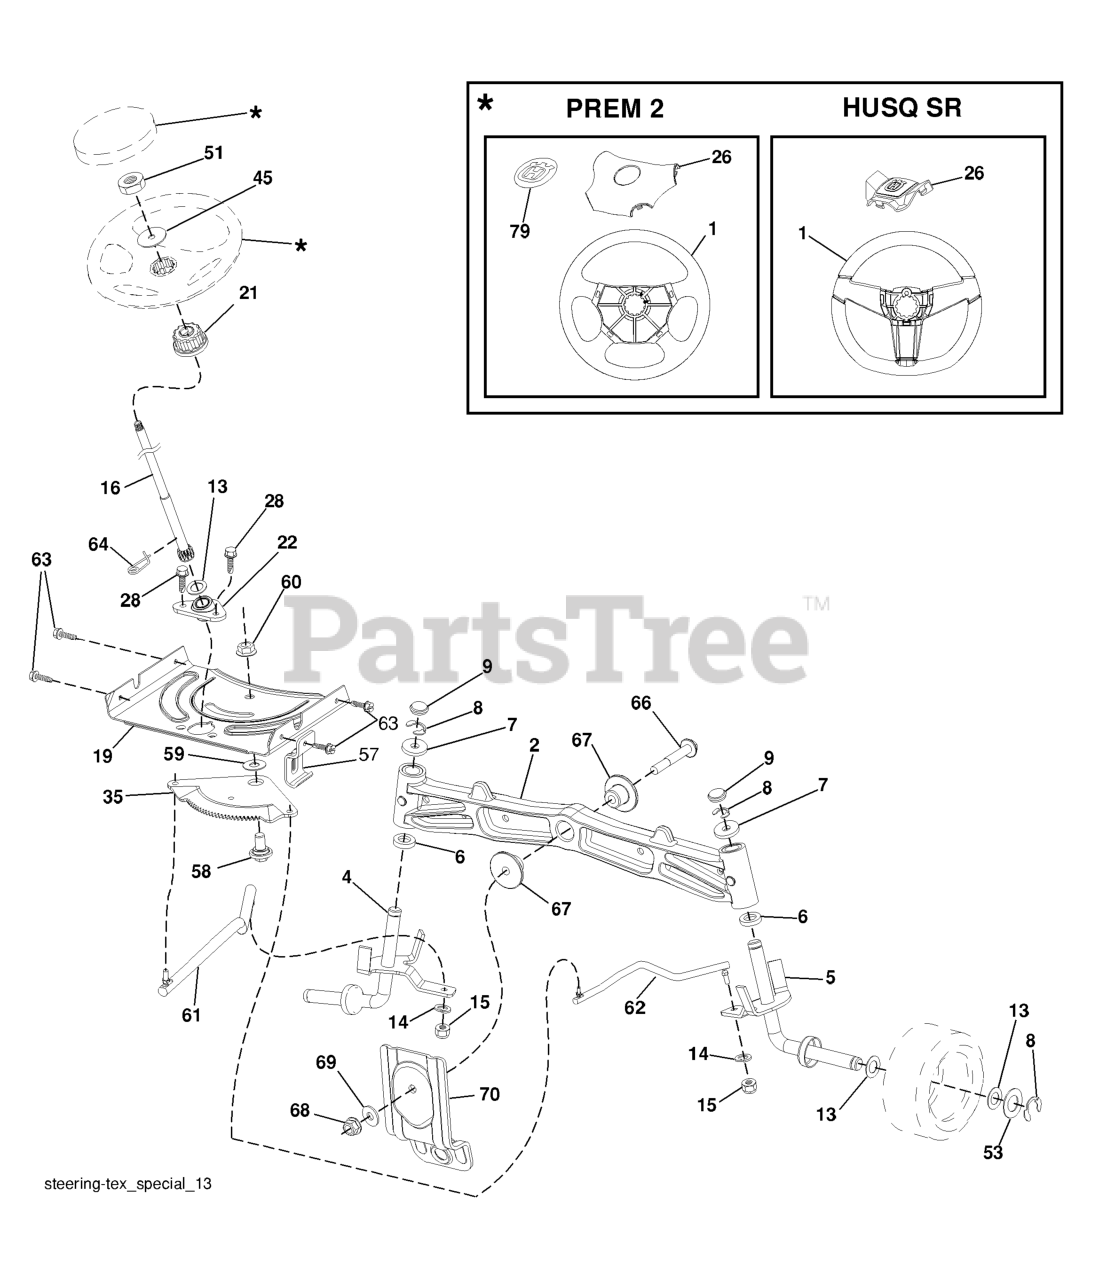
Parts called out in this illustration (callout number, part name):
1	RP WHEEL.STEER.HUSQ.PREM.OVMLD
2	AXLE.CAST.IRON
4	SPINDLE.WELDED.LH.15"TEX
5	SPINDLE.WELDED.RH.15"T
6	THRUST WASHER
9	CAP.SPINDLE.BLACK
14	WASHER, LOCK 3/8
15	NUT CROWNLOCK 3/8-24
16	SHAFT, STEERING
19	PLATE.STEER.DDL.NLT/NG
21	ADAPTER, WHEEL STNG..
22	BUSHING.ASM.STEERING.A
26	RP INSERT.CAP.WHL.STRG.HUSQ.
28	SCREW, 3/8-16X3/4
35	GEAR.SECTOR.PLATE.DDL.
45	WASHER 9/16"ID, 2 3/8"OD
51	NUT.HEX.1/2-20
53	WASHER.HARDENED
57	BRKT.UPSTOP.GT/LT.TEX
58	BOLT.SHOULDER.SECTOR.P
59	WASHER.THURST.SECTOR.S
60	NUT FLANGE LOCK 5/8-11
61	DRAGLINK.LH.BALLSTUD.D
62	DRAGLINK.RH.BALLSTUD.D
63	SCREW
64	RETAINER.CLIP.SPRING.S
66	BOLT HEX FGHD 7/16-14 X 3 SERR
67	BUSHING.PM.FRONT AXLE
68	NUT.LOCK.FLANGE.7/16
69	WASHER.1.5X.505X.118
70	BRKT.DECK.SUSPENSION.F
